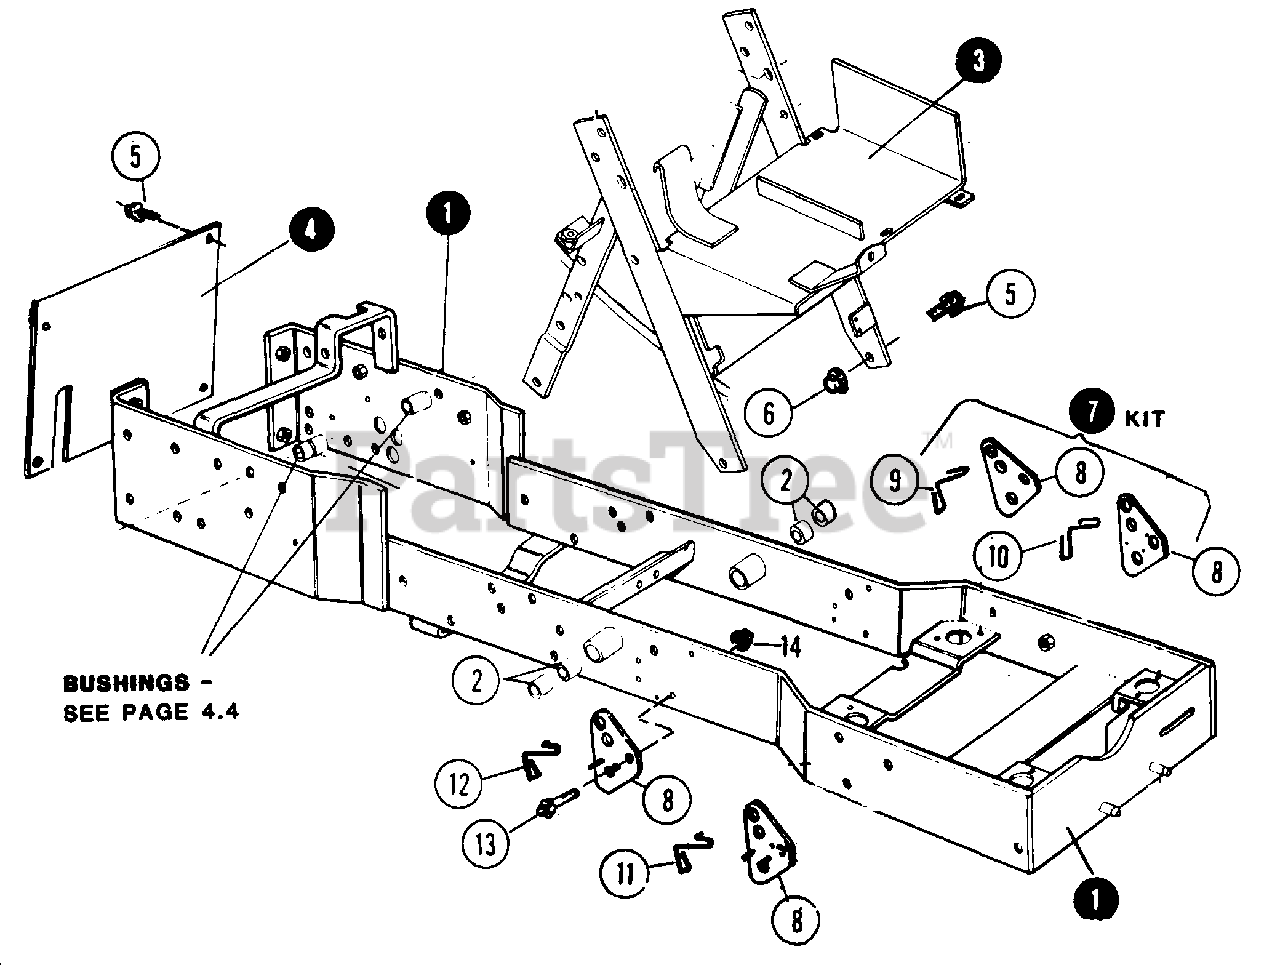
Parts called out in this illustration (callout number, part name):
1	FRAME ASSEMBLY
2	BUSHING
3	PEDESTAL FRAME
4	PLATE, REAR COVER
5	BOLT, 3/8C x 1 FLANGE
6	NUT, 3/8C FLANGE LOCK
7	KIT, IMPLEMENT MOUNTING
8	BRACKET, LINK PIVOT
9	SPRING, LEFT REAR
10	SPRING, LEFT FRONT
11	SPRING, RIGHT FRONT
12	SPRING, RIGHT REAR
13	BOLT, 5/16-18 x 1 HEX FLANGE LOCK
14	NUT, 5/16-18 HEX LOCK
